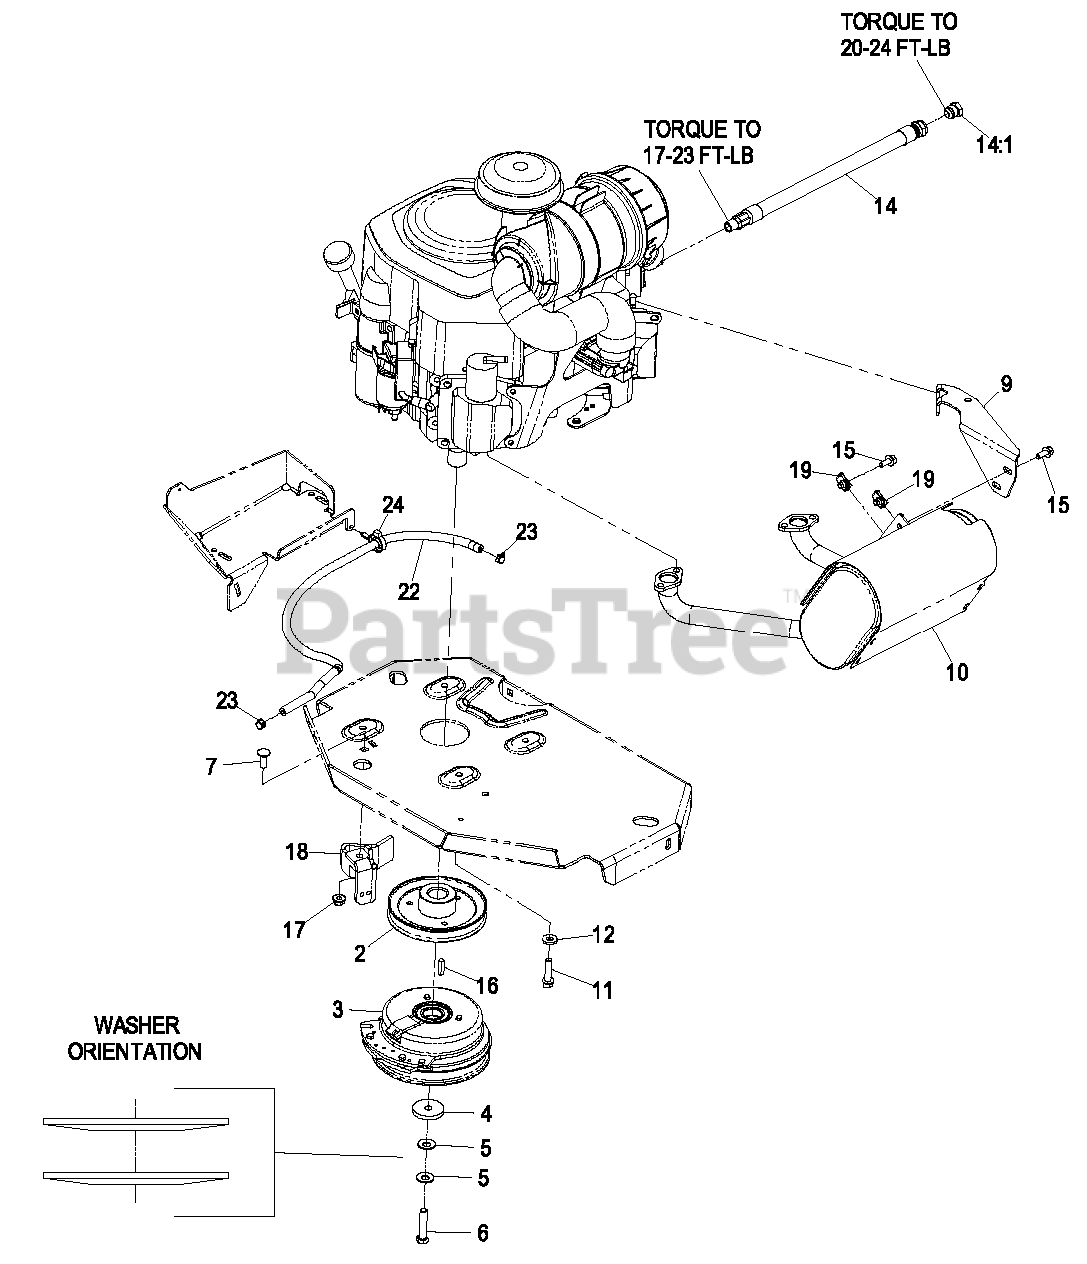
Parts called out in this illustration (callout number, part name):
2	SHEAVE
3	CLUTCH KIT
4	WASHER-CLUTCH
5	WASHER-SPRING
6	SCREW-HH W/LOCTITE
7	SCREW-CARR
11	SCREW-HWH
12	WASHER-BELLEVILLE
15	SCREW-HHF
17	NUT-HF, NI
18	CLUTCH-ANCHOR
22	HOSE-FUEL
23	CLAMP-HOSE
24	CLAMP-HOSE
27	WASHER-SPRING
28	SCREW-HH
